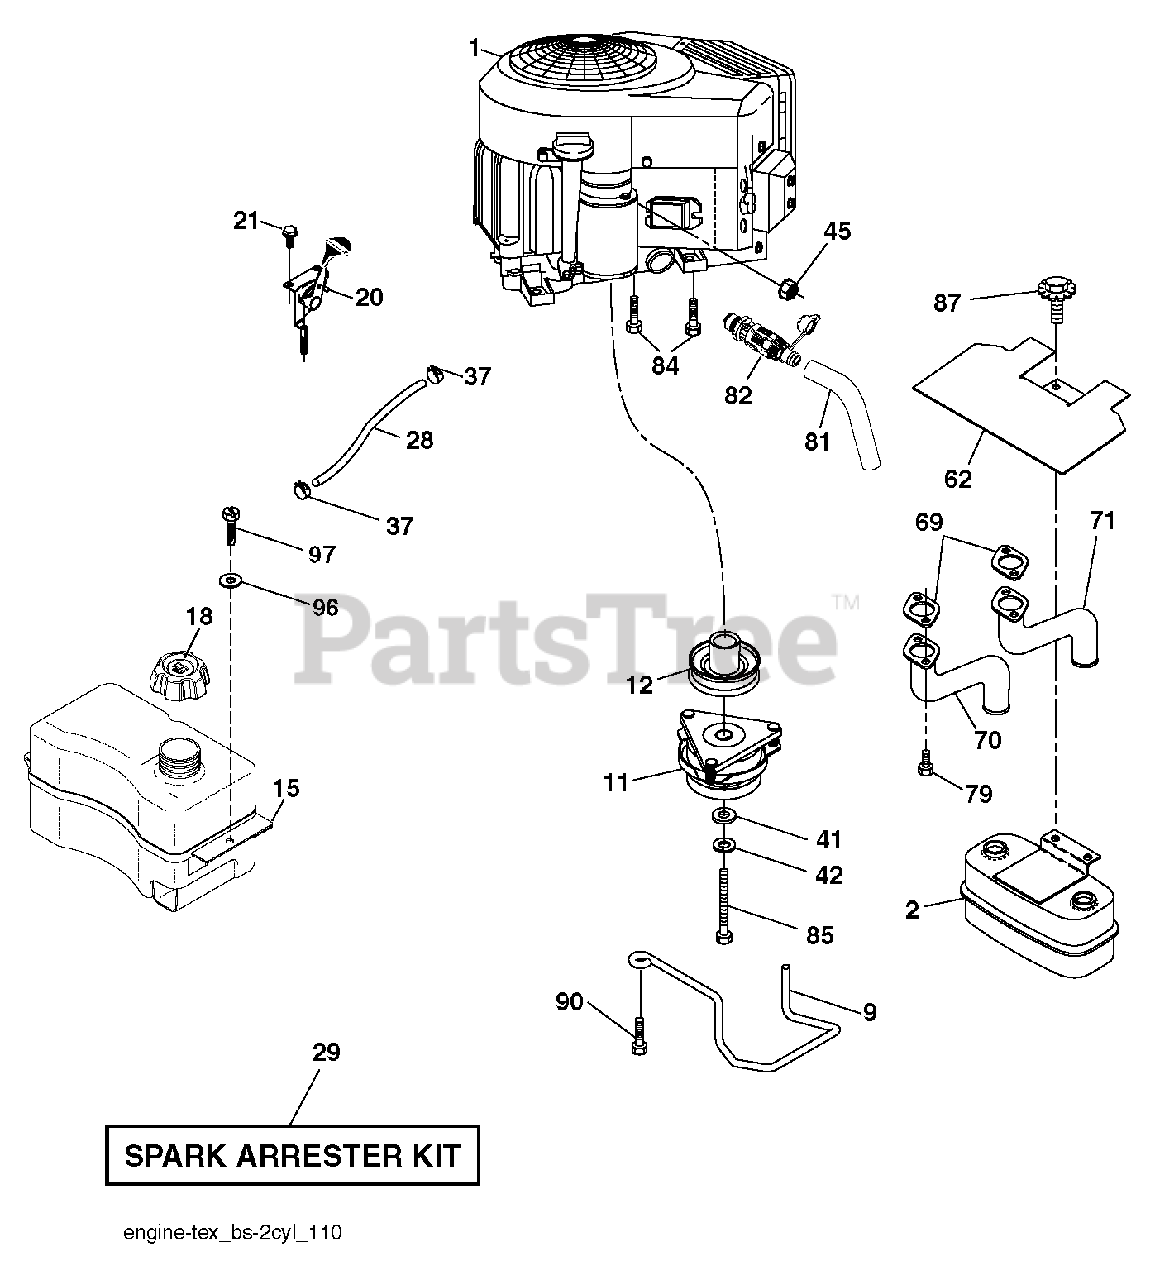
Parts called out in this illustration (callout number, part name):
2	MUFFLER.ASM.TWN.EXTNDED.DFLCTR
9	KEEPER BELT ENGINE
11	CLUTCH.ELECTRIC.LT.48"*
12	PULLEY.ENGINE.TUFFTORQ
15	TANK.ASSEMBL.2.5GAL.NON-EPA
18	CAP ASM.FUEL.2.25"FR.
20	CONTROL.TH/CK.COBRA.B&S.TWN.
21	SCREW.#10 X 0.750.BOS
28	LINE.FUEL.20
29	KIT.SPARK ARRESTOR 794945 B&S
37	HOSE CLAMP
42	LOCKWASHER
45	NUT
62	SHIELD.HEAT.MUFFLER
69	GASKET.MUFFLER
70	RP.EXHAUST.TUBE.LH.BS/TWIN
71	EXHAUST.TUBE.RH.BS/TWIN
79	SCREW.SOCKET.HEAD.5/16-18
81	TUBE, DRAIN OIL ASM.
82	VALUE.OIL.DRAIN
84	SCREW.3/8-16
85	BOLT HEX 7/16-20X4-1/4"
87	BOLT, 5/16-18 X 1 3/4
90	SCREW 3/8-16X1
